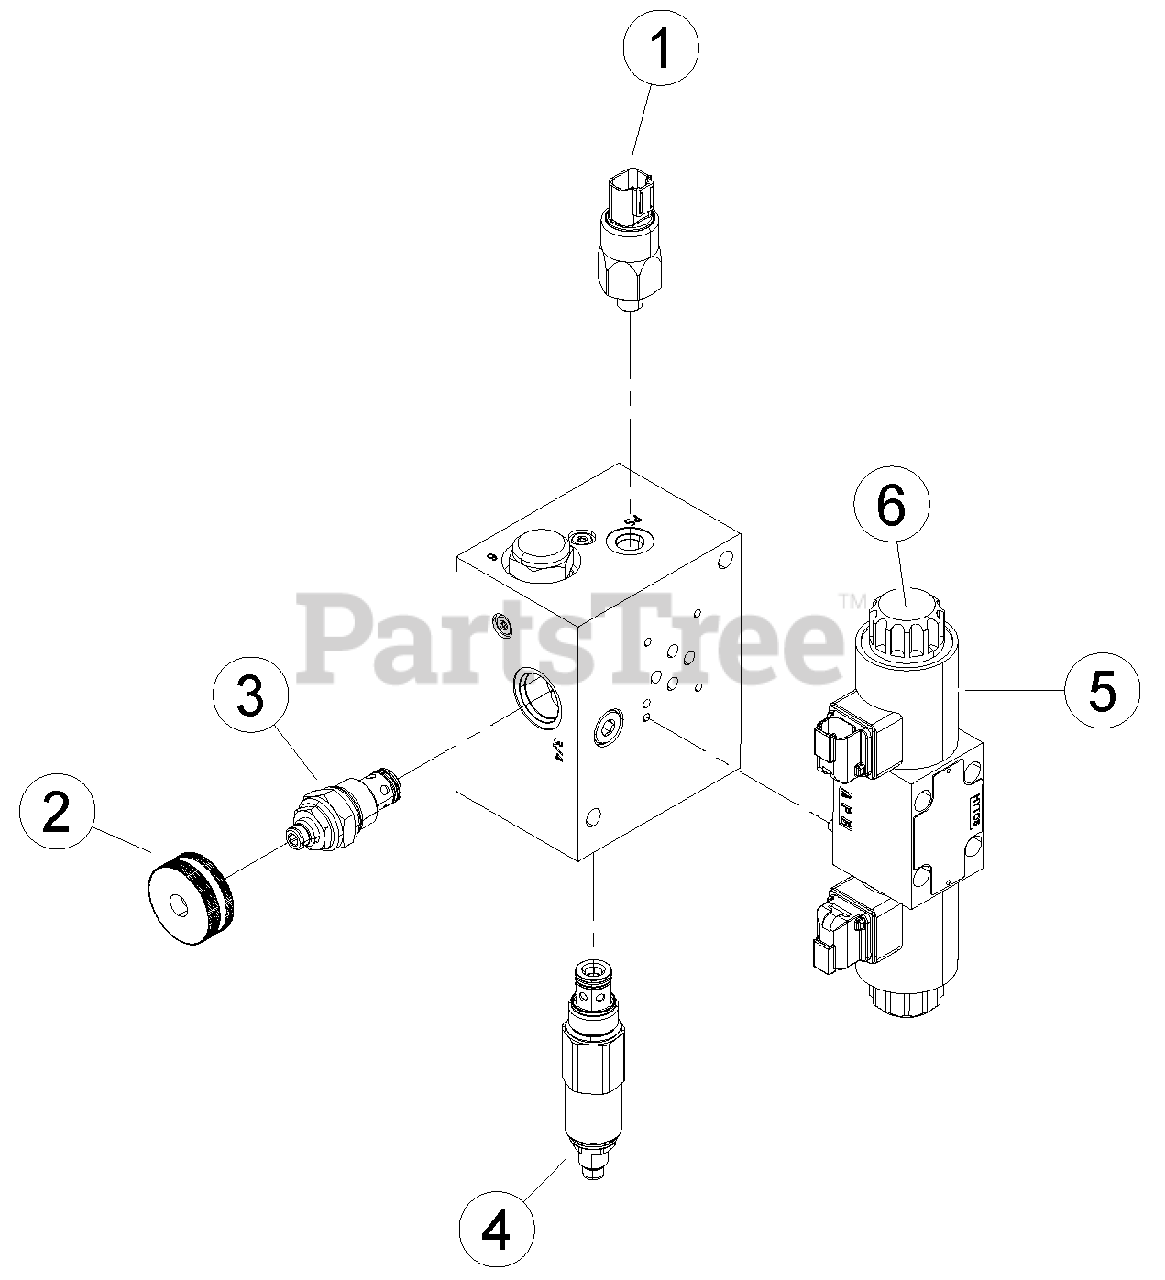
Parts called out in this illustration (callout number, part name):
1	SWITCH, PRESSURE GC
2	KIT, VALVE KNOB
3	VALVE, NEEDLE - 10 MOUNT
4	VALVE, DIFFERENTIAL SENSING
5	COIL, SOLENOID
6	NUT, COIL SOLENOID
